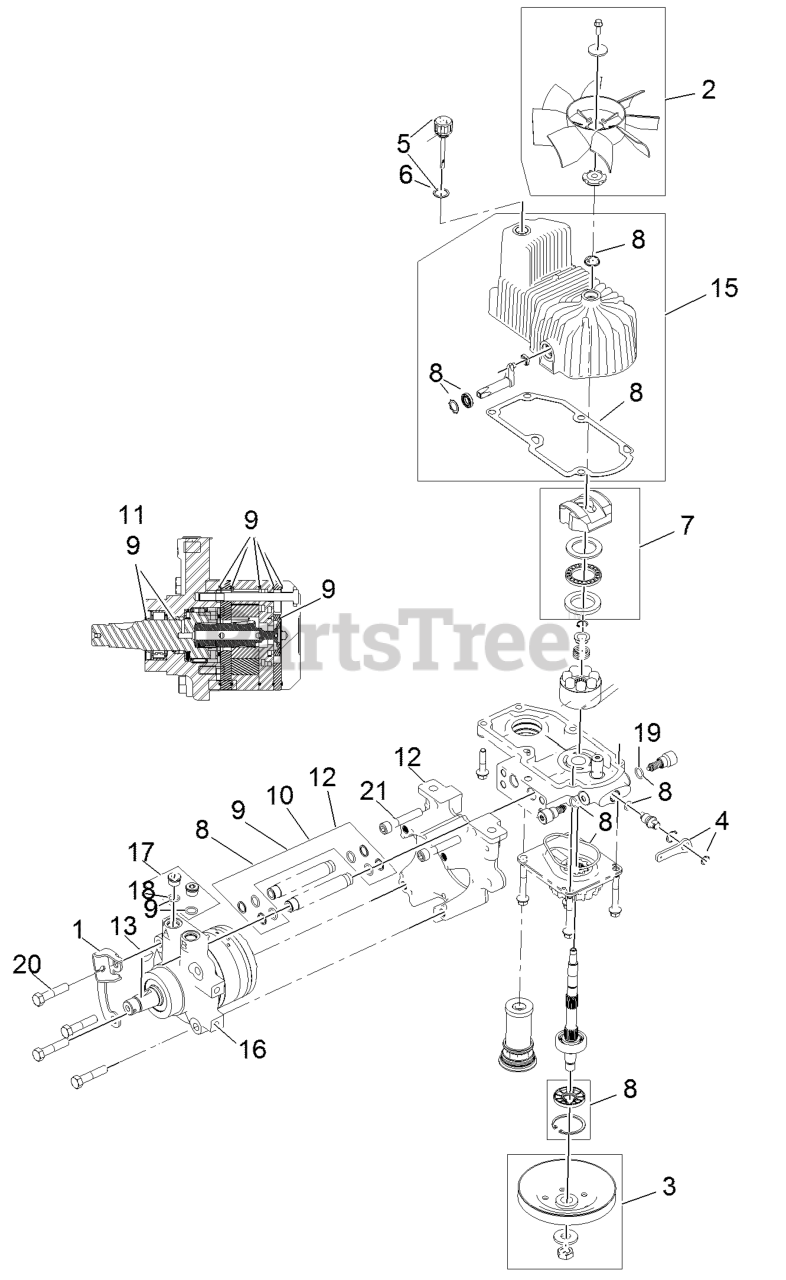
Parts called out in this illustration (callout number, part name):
1	BRACKET-ANCHOR, CABLE
2	FAN KIT
3	PULLEY KIT
4	HANDLE-BYPASS VALVE, HYDRO
5	DIPSTICK-HYDRO W/GASKET
6	GASKET-DIPSTICK, HYDRO
7	SWASH BLOCK KIT
8	PUMP SEAL KIT
9	MOTOR SEAL KIT
10	TUBE SEAL KIT
11	OUTPUT SHAFT SEAL KIT
12	NOSE CUP-UHT
13	KEY-WOODRUFF
15	HOUSING-HYDRO, LH
16	MOTOR-HYDRAULIC LH 240CC
17	MAGNETIC PLUGS SERVICE KIT
19	O-RING-CHECK VALVE
20	SCREW HH
21	SCREW-HSH
